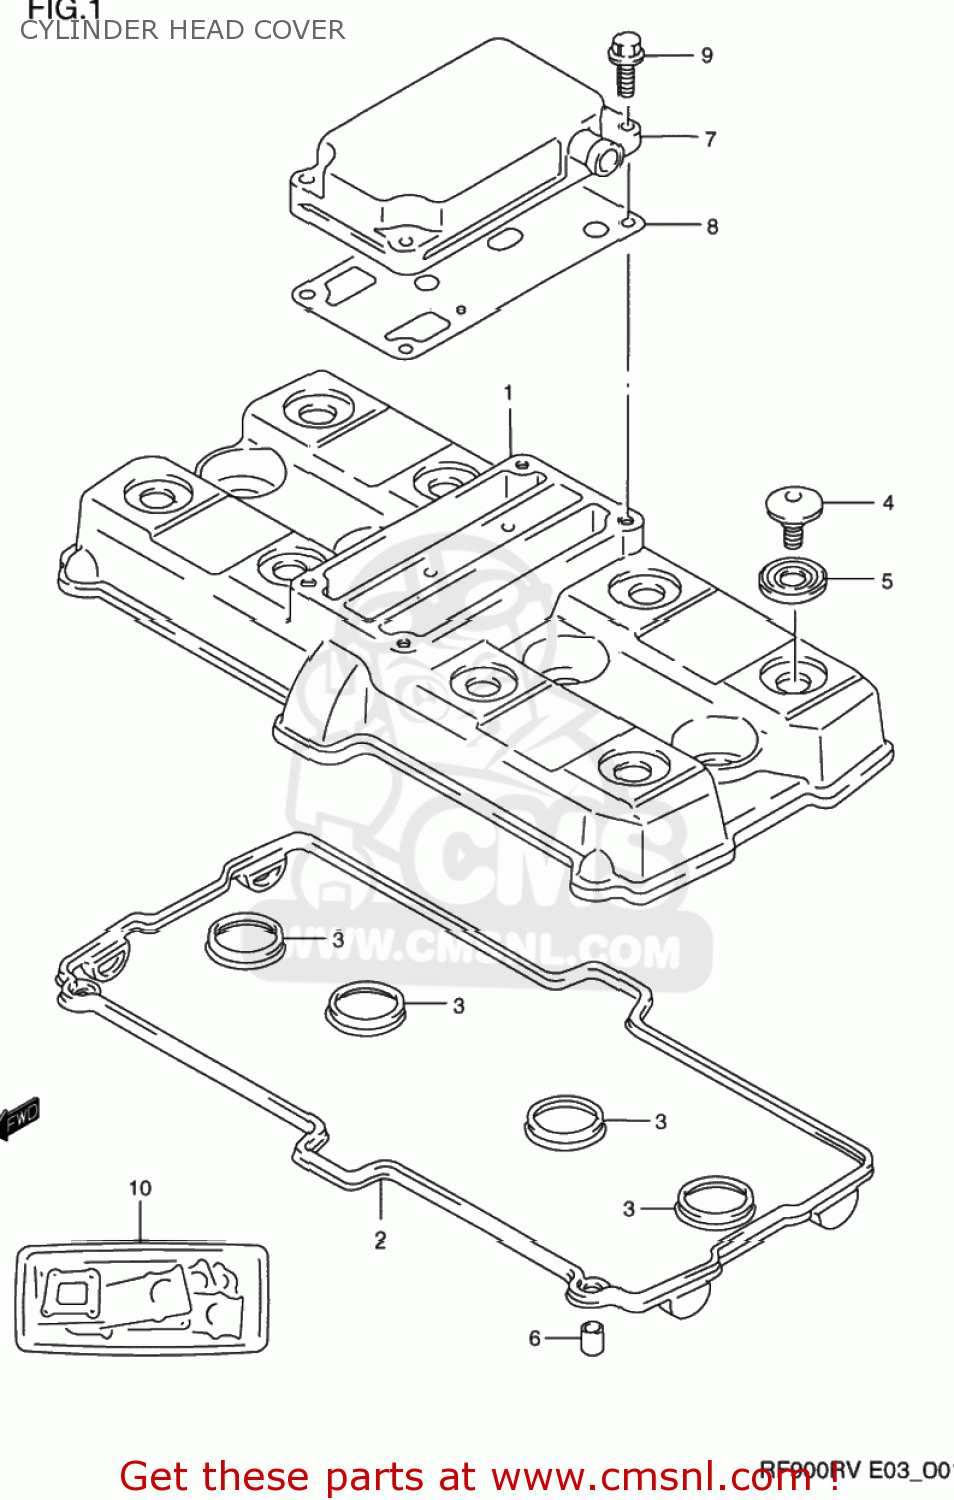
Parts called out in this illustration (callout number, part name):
1	COVER,CYLINDER HEAD
2	GASKET,CYL HEAD COVER NO.1
3	GASKET,CYL HEAD COVER NO.2
4	BOLT(7X17.5)
5	WASHER(10.6X25.5X2.3)
6	PIN(6.2X8X11)
7	COVER,BREATHER
8	GASKET,BREATHER COVER
9	BOLT
10	GASKET SET (NAS)
